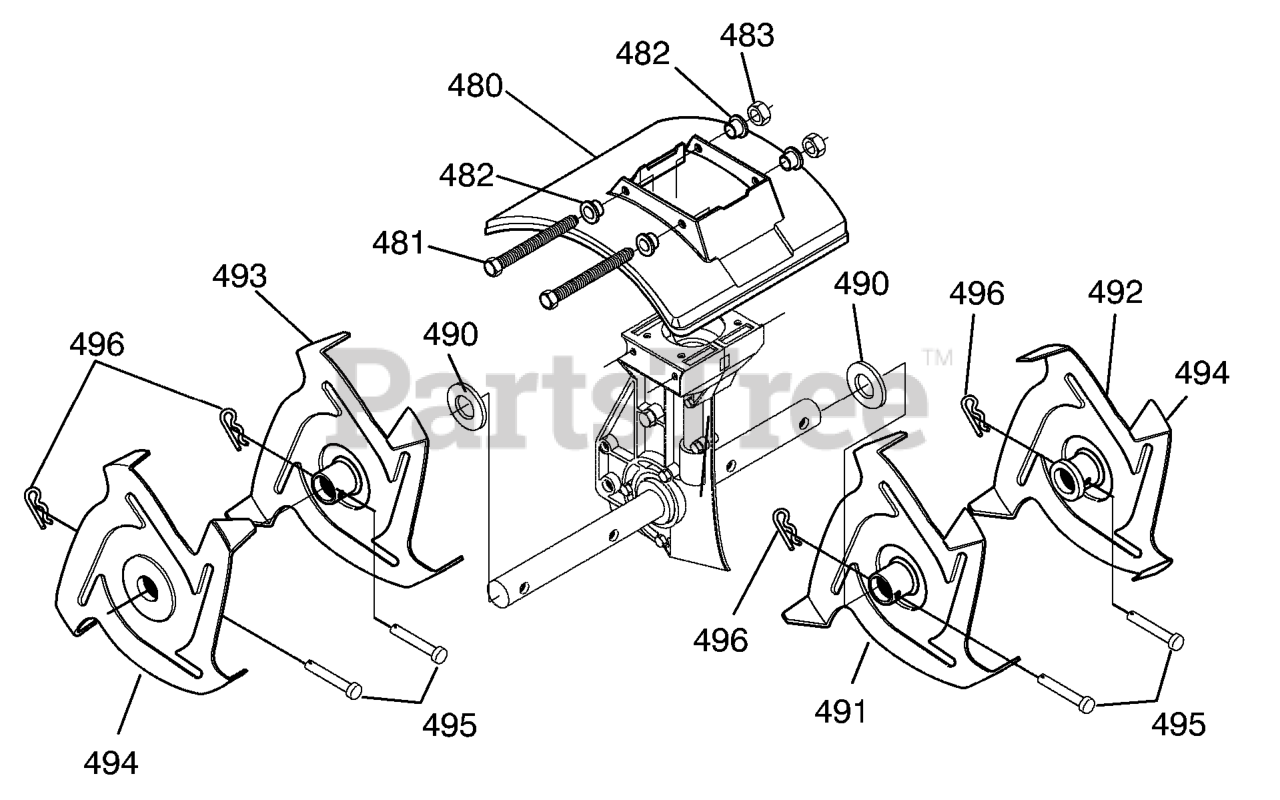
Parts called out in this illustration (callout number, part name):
480	Shield, Tine
481	Screw, 1/4-20x5.50
482	Spacer, Flange
483	Nut, 1/4-20
490	Washer, Felt
491	Tine Assy. Inner LH
492	Tine Assy. Outer LH
493	Tine Assy. Inner RH
494	Tine Assy. Outer RH
495	Clevis Pin
496	Hair Pin
